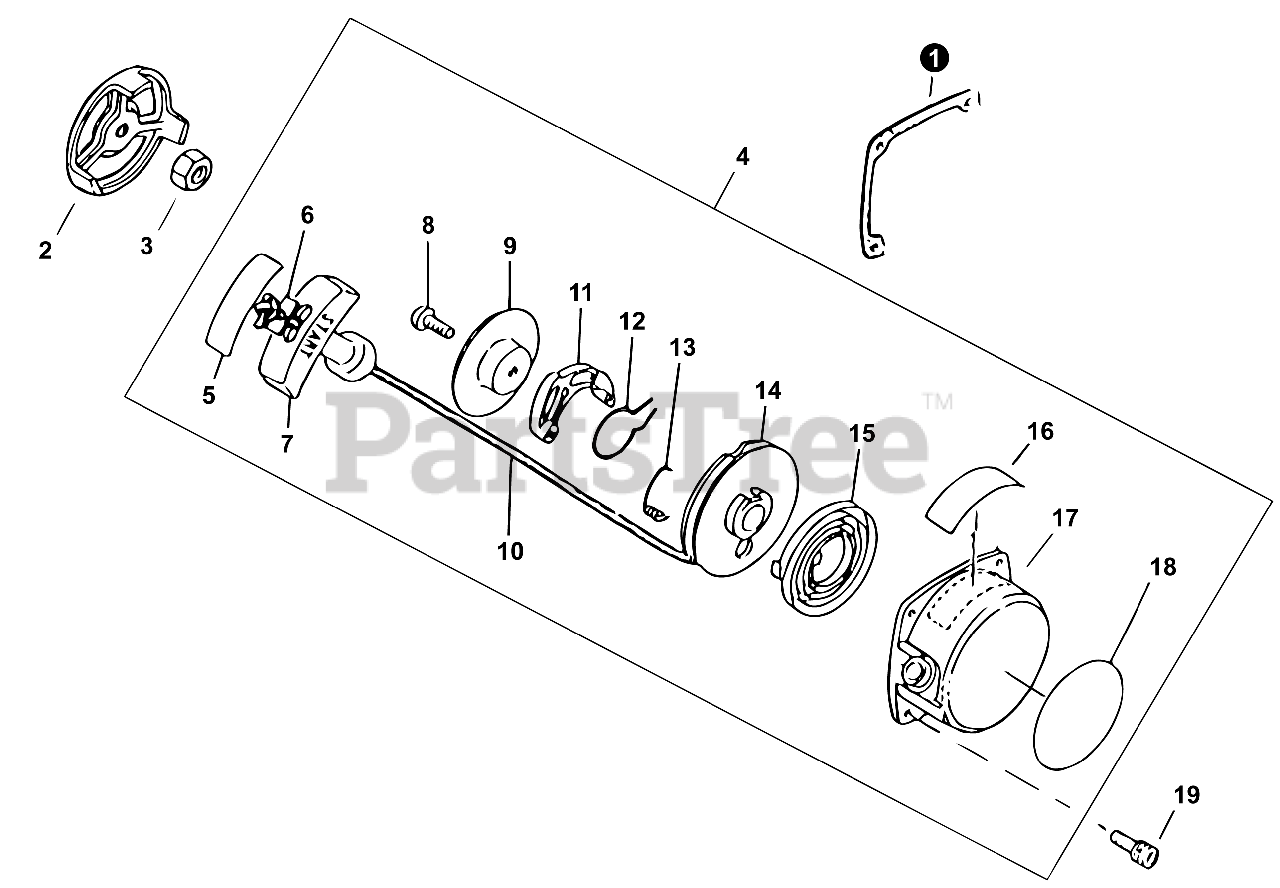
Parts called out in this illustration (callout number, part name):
1	RECOIL STARTER GASKET
2	STARTER PULLEY
3	NUT M8×H5
4	RECOIL STARTER ASSY
5	TAPE
6	ROPE STOPPER
7	STARTER HANDLE
8	SCREW
9	FRICTION PLATE
10	STARTER ROPE
11	RATCHET
12	FRICTION SPRING
13	RETURN SPRING
14	ROPE REEL
15	RECOIL SPRING
16	TAPE
17	RECOIL STARTER CASE
18	LABEL TRADE
19	BOLT SPW M4×16
